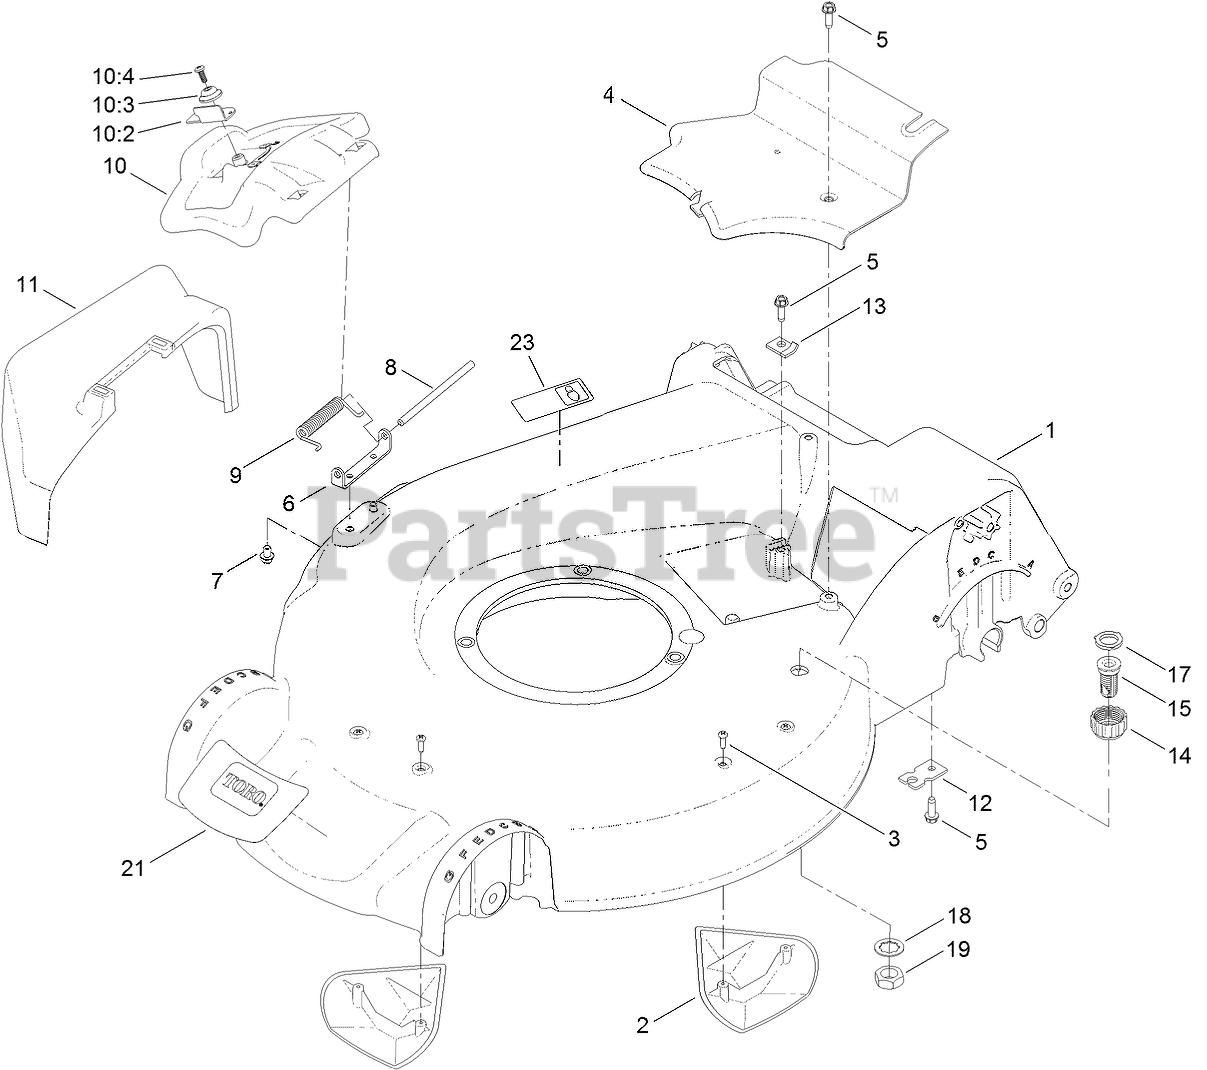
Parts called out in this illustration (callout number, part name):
1	HOUSING ASM
2	KICKER-HOUSING
3	SCREW-PPH
4	COVER-BELT
5	SCREW-HWHTF
6	BRACKET-COVER
7	SCREW-HWH
8	ROD-COVER
9	SPRING-TORSION
10	DISCHARGE DOOR ASM
10:2	LATCH-DOOR
10:3	CAP-DOOR
10:4	SCREW-PLASTITE
11	CHUTE-DISCHARGE, SIDE
12	BRACKET-CABLE, TRACTION
13	CLAMP-CABLE
14	COUPLING-HOSE, WASHOUT PORT
15	PORT-WASHOUT
17	WASHER-SEAL, WASHOUT PORT
18	WASHER-TOOTH, INTERNAL
19	NUT-JAM
21	DECAL-DECK
23	DECAL-PLACEMENT, FOOT
